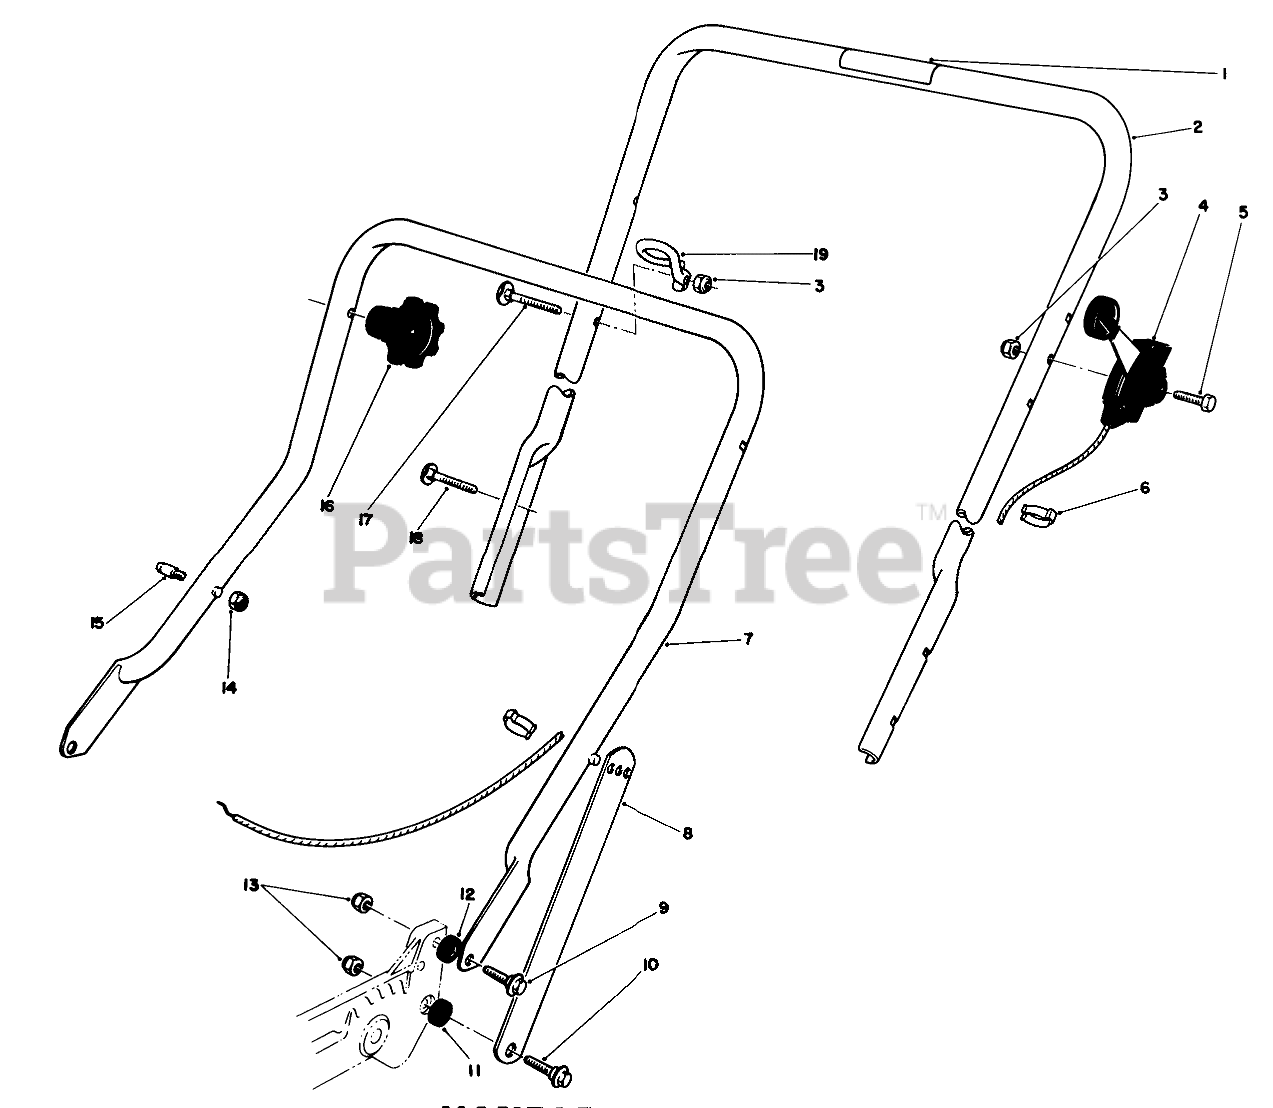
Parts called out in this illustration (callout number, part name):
1	Decal-Danger
2	Handle-Upper (Incl. Ref. #1) (Used on Units With Serial No. 7000001-7004102)
2	Handle-Upper (Incl. Ref. #1) (Used on Units With Serial No. 7004103 & Up)
3	NUT-LOCK, NI
4	SERVICE THROTTLE CONTRO
5	SCREW-HH
6	BOWDEN CLIP
7	LOWER HANDLE ASM
8	Handle Latch
9	SCREW-SHOULDER
10	SCREW-SHOULDER
11	SPACER
12	SPACER
13	NUT-LOCK, NI
14	NUT-LOCK, NI
15	HANDLE PIN
17	HANDLE SCREW
18	5/16-18 X 2 HNDLE SCREW
19	Guide
